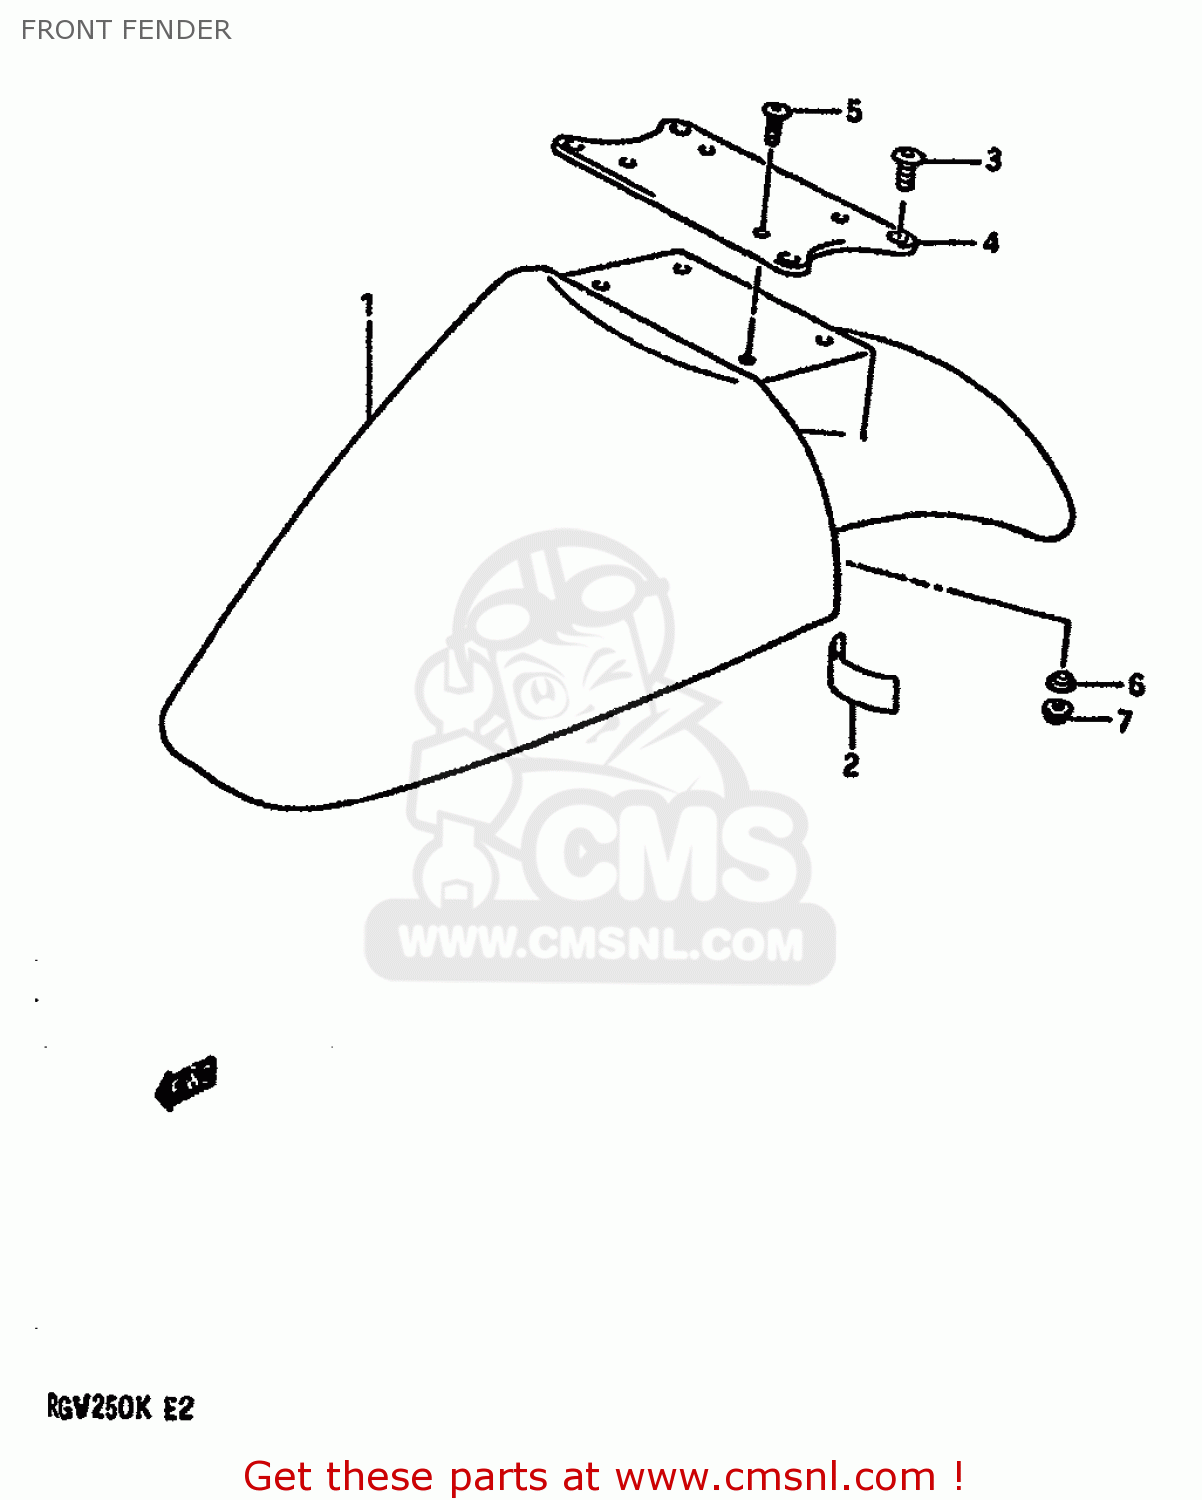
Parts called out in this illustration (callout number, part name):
1	FENDER,FRONT (BLUE)
2	CUSHION,BODY COWLING
3	SCREW(6X12)
4	BRACE,FR FENDER
5	SCREW(5X16)
6	WASHER
7	NUT
